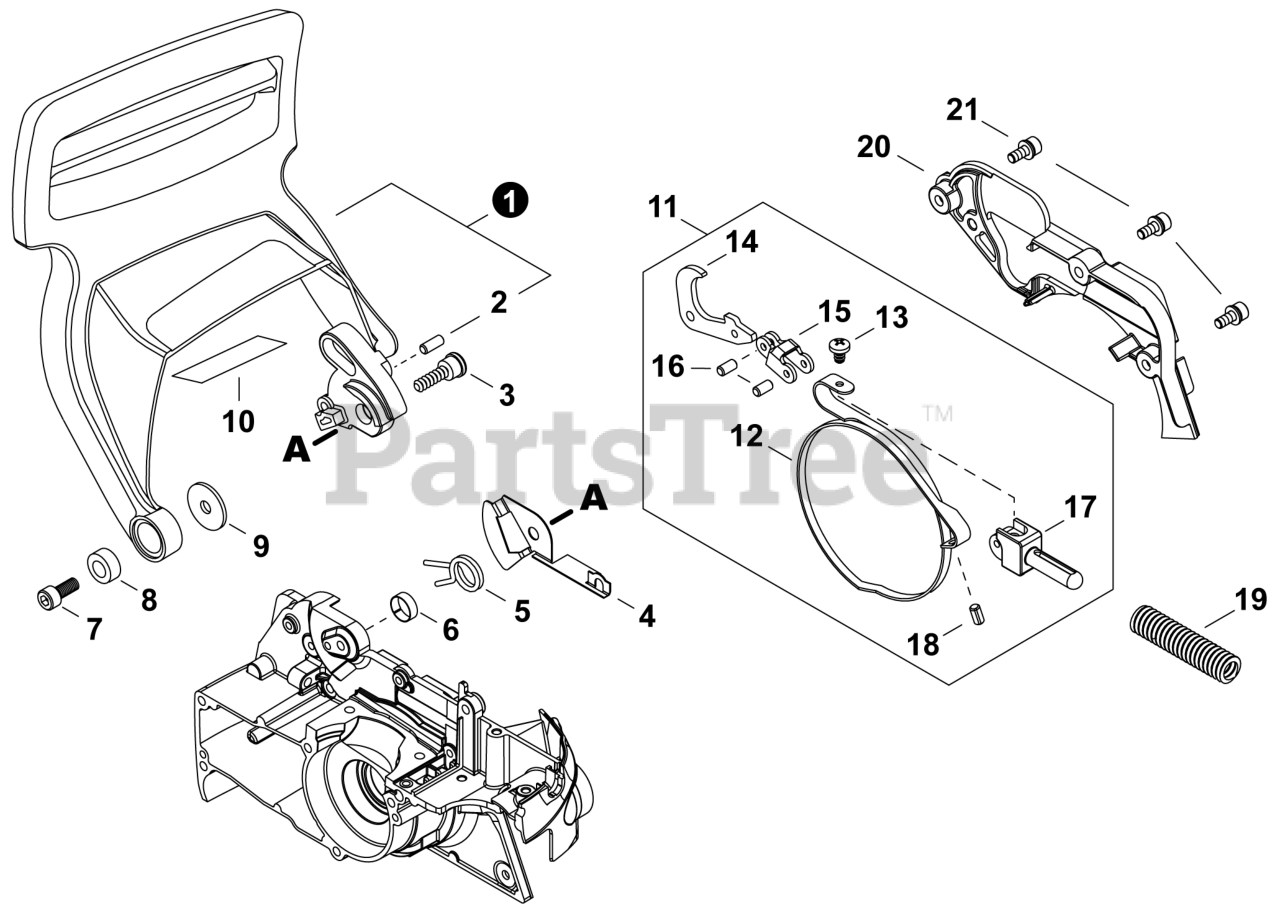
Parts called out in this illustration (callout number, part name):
1	GUARD ASSY, HAND
2	PIN, LOCATING 4x8
3	BOLT, ADHESIVE M4x38
4	PLATE, RETAINING
5	SPRING, TORSION
6	COLLAR 8
7	BOLT, ADHESIVE 5
9	WASHER 5
10	SHIELD, HEAT 35x60x0.10
11	BRAKE ASSY, BAND
12	BAND, BRAKE
13	SCREW, TAPPING M4x10
14	LEVER, BRAKE
15	STRAP, CABLE
16	PIN 3x12
17	CONNECTOR, BRAKE
18	PIN, SPRING 4x10 MM
19	SPRING, BRAKE
20	COVER, BRAKE
21	BOLT, ADHESIVE M4x10
